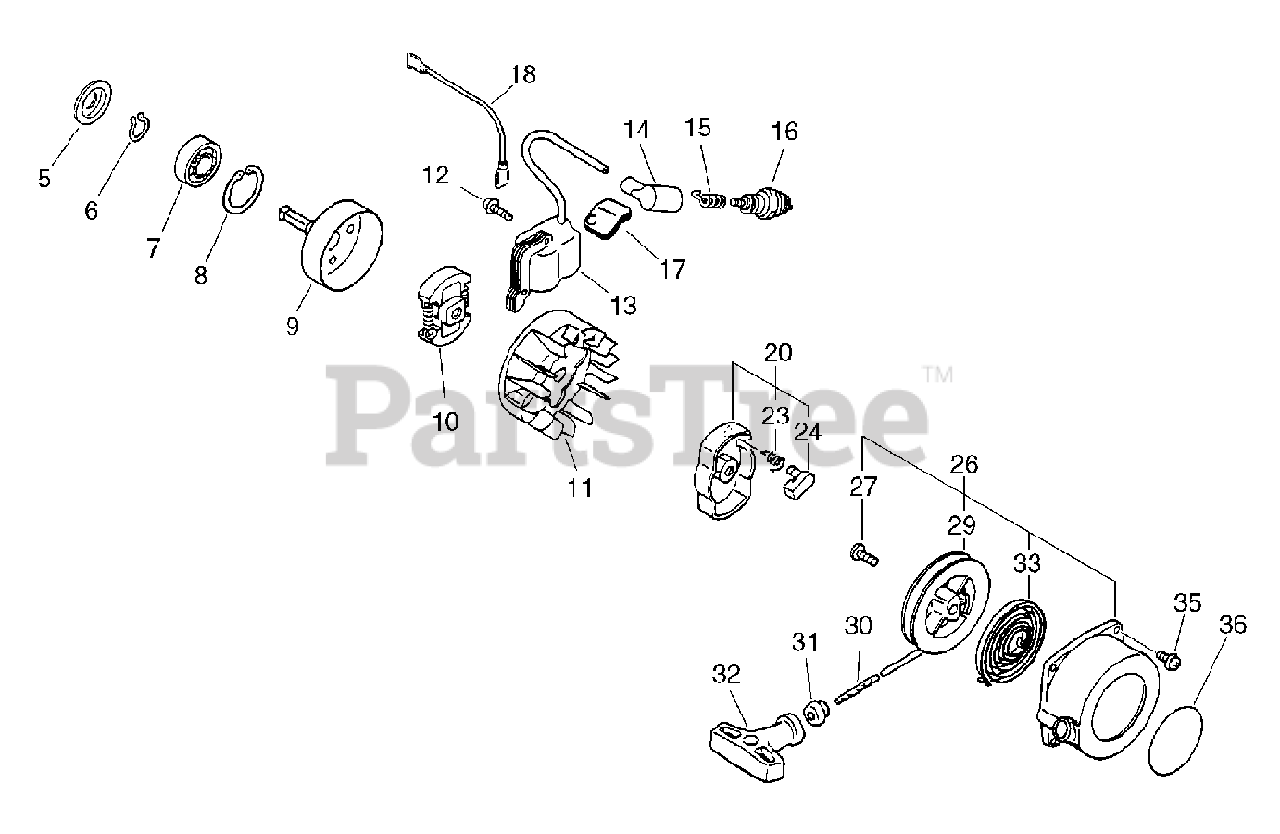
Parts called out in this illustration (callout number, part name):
5	Stopper
6	Circlip 12
7	Bearing, Ball 6201
8	Circlip 32
9	Drum, Clutch
10	Clutch Assembly
12	Screw 4*22
13	Coil, Ignition
14	Cap, Spark Plug
15	Coil, Spark Plug
16	Plug, Spark (RCJ-7Y)
18	Lead, Ground
20	Pawl Assy, Starter
23	Spring, Return
24	Pawl, Starter
26	Starter Assy
27	Screw
29	Drum, Starter
30	Rope, Starter
31	Guide, Rope
32	Grip, Starter
33	Spring, Rewind
35	Screw 4*16
36	Label, Echo
